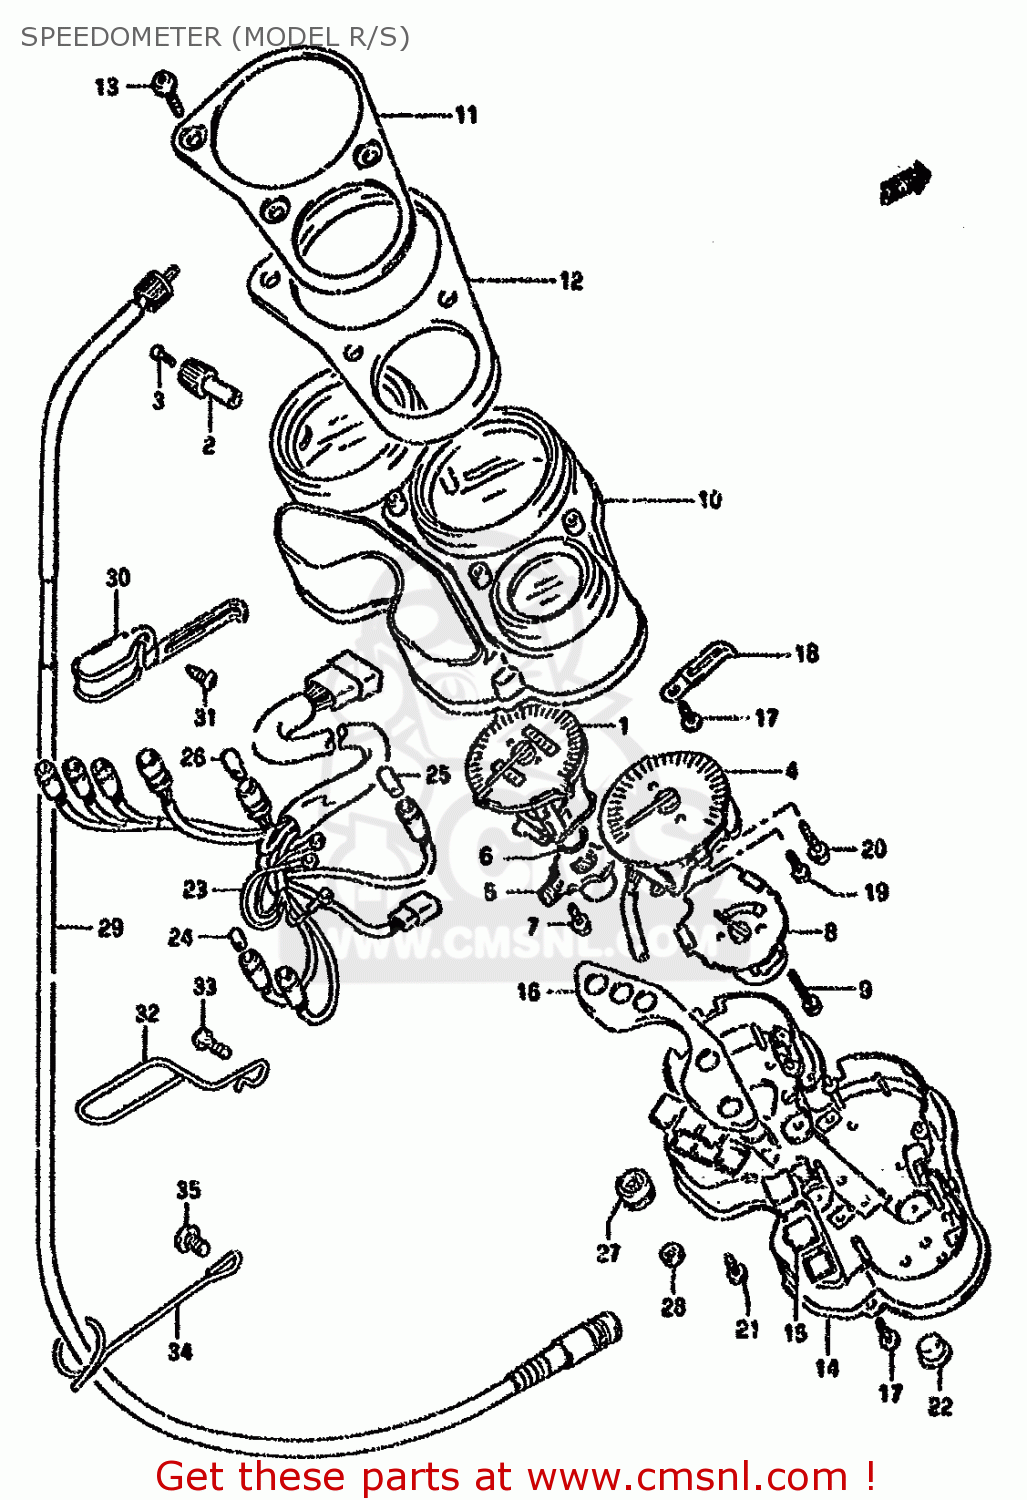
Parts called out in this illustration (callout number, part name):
1	SPEEDOMETER
2	KNOB,TRIP
3	SCREW(2X6)
4	TACHOMETER
5	GEAR BOX,SPEEDOMETER
6	O RING
7	SCREW
8	METER,TEMPERATURE
9	SCREW(3X22)
10	HOOD
11	PANEL,METER
12	CUSHION
13	SCREW
14	CASE,METER
15	LENS SET
16	PANEL
17	SCREW(4X14)
18	CLAMP
19	SCREW
20	SCREW(4X22)
21	SCREW
22	CAP
23	SOCKET
24	BULB(12V3W,T6.5)
25	BULB(12V1.7W,T6.5)
26	BULB(12V1.7W,T10,WB121)
27	CUSHION,METER
28	NUT
29	CABLE ASSY,SPEEDOMETER
30	GUIDE,METER CABLE NO.1
31	SCREW 5X8
32	GUIDE,METER CABLE NO.2
33	SCREW
34	GUIDE,SPEEDOMETER CABLE,R
35	SCREW 6X10
36	CABLE ASSY,SPEEDOMETER
37	GUIDE,SPEEDOMETER CABLE
38	SCREW
39	NUT
40	GUIDE,SPEEDOMETER CABLE NO.3
41	SCREW
42	SCREW
